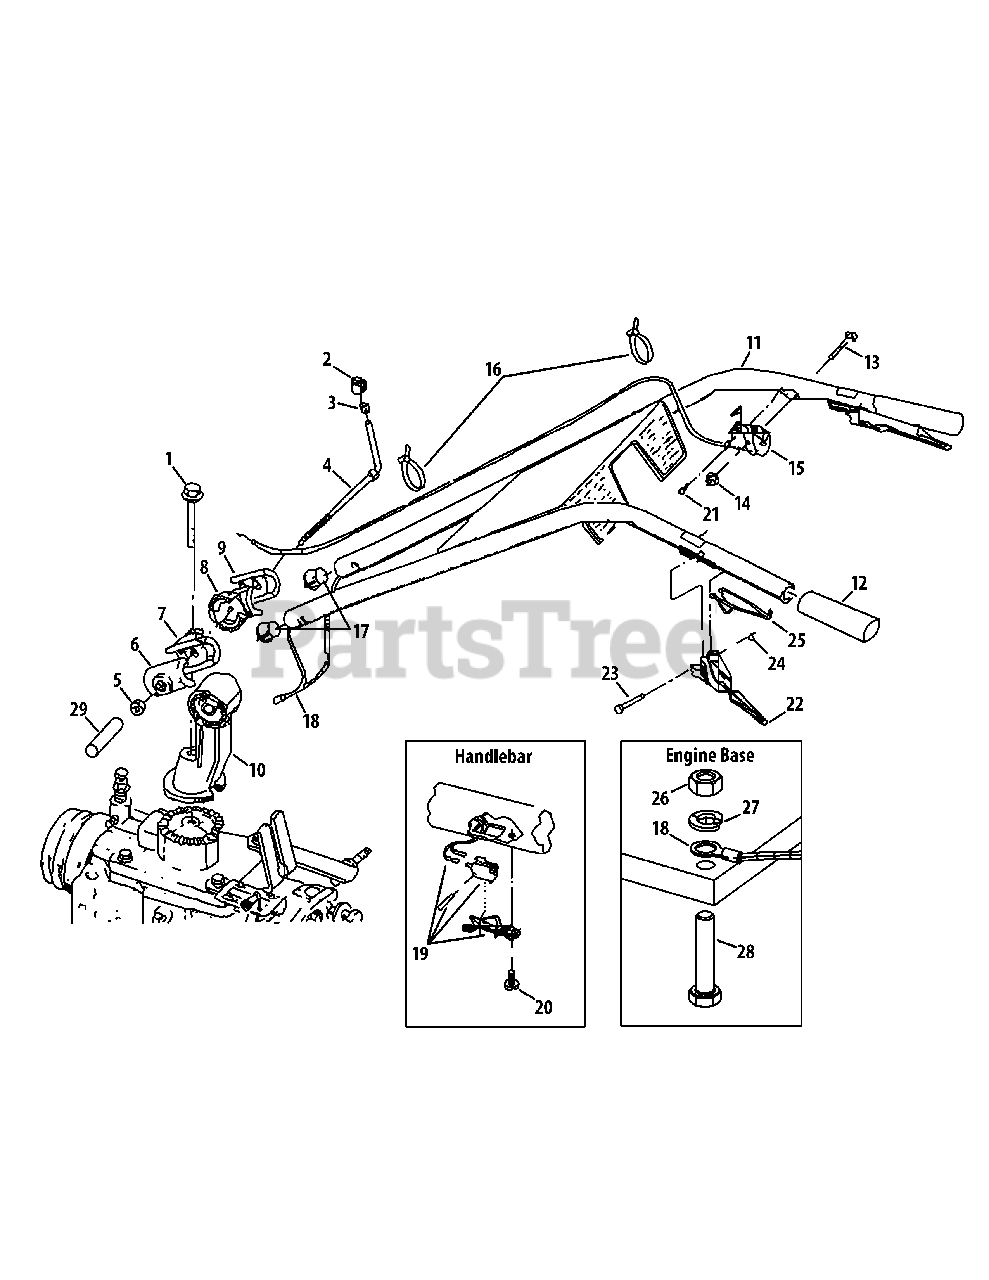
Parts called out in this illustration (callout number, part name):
1	Hex Bolt, 1/2"-13 x 3-1/2"
2	Handlebar Height Adjustment Knob
3	Retaining Ring
4	Handlebar Height Adjustment Stud
5	Hex Nut, 1/2"-13
6	Handlebar Hgt, Adj Clamp (LT)
7	Handlebar Hgt Adj Ratchet (LT)
8	Handlebar Hgt Adj Ratchet (RT)
9	Handlebar Hgt Adj Clamp (RT)
10	Handlebar Mounting Base
12	Handlebars Grip
13	Curved Head Bolt, 1/4"-20 x 2"
14	Hex Nut, 1/4"-20
15	Throttle Control & Cable, 66"
16	Plastic Tie
17	Wire Harness Retainer Plug
18	Handlebar Wire Harness Assembly
19	Switch Assembly
20	Pan Head Screw, #10-16 x 1/2"
21	Phillips Head Screw, 10-32 x 1/2"
22	Operator Presence Control Lever
23	Pivot Pin
24	Retaining Ring
25	Return Spring
26	Hex Nut, 5/16"-18
27	Washer, 5/16"
28	Hex Head Screw, 5/16"-18 x 15
